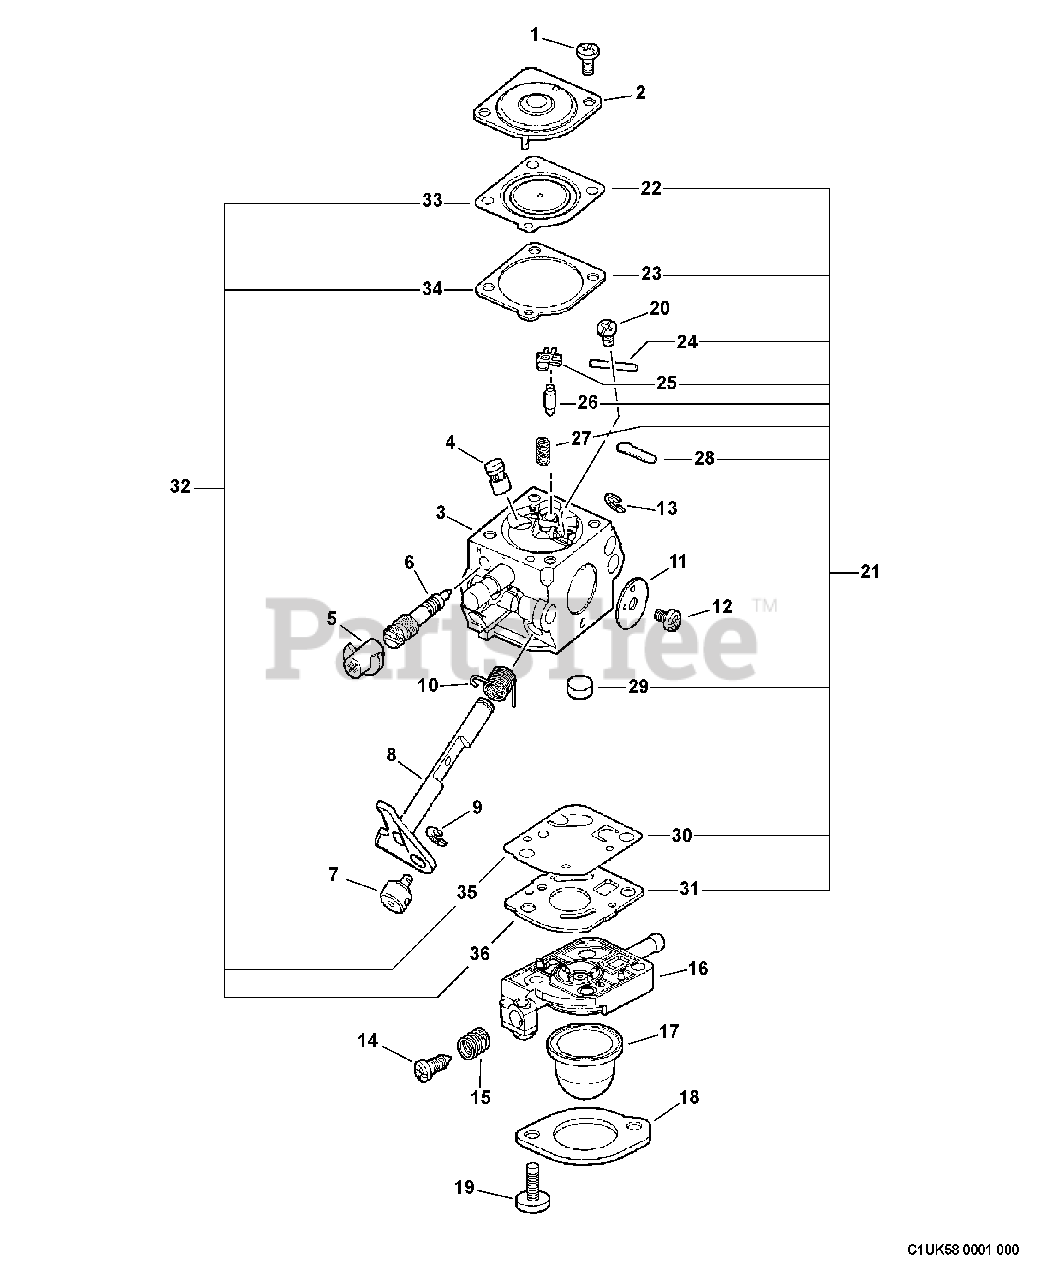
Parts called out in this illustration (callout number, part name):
2	COVER, METERING
3	BODY, CARBURETOR
4	NOZZLE, CHECK VALVE
5	CAP, LIMITER
6	NEEDLE - HIGH SPEED
8	SHAFT, THROTTLE
9	RING, RETAINING
10	SPRING, RETURN
11	VALVE, THROTTLE
13	RING, RETAINING
14	SCREW, IDLE ADJUST
15	SPRING, IDLE ADJUST
16	BASE, PURGE
17	BULB, PURGE
18	RETAINER, PURGE BULB
19	SCREW, RETAINER
20	SCREW, METERING LEVER PIN
21	REPAIR KIT
22	DIAPHRAGM, METERING
23	GASKET, DIAPHRAGM
24	PIN, METERING LEVER
25	LEVER, METERING
26	VALVE, INLET NEEDLE
27	SPRING, METERING LEVER
28	PLUG, WELCH
29	STRAINER
30	DIAPHRAGM, PUMP
31	GASKET, PUMP
32	DIAPHRAGM/GASKET KIT
33	DIAPHRAGM, METERING
34	GASKET, DIAPHRAGM
35	DIAPHRAGM, PUMP
36	GASKET, PUMP
